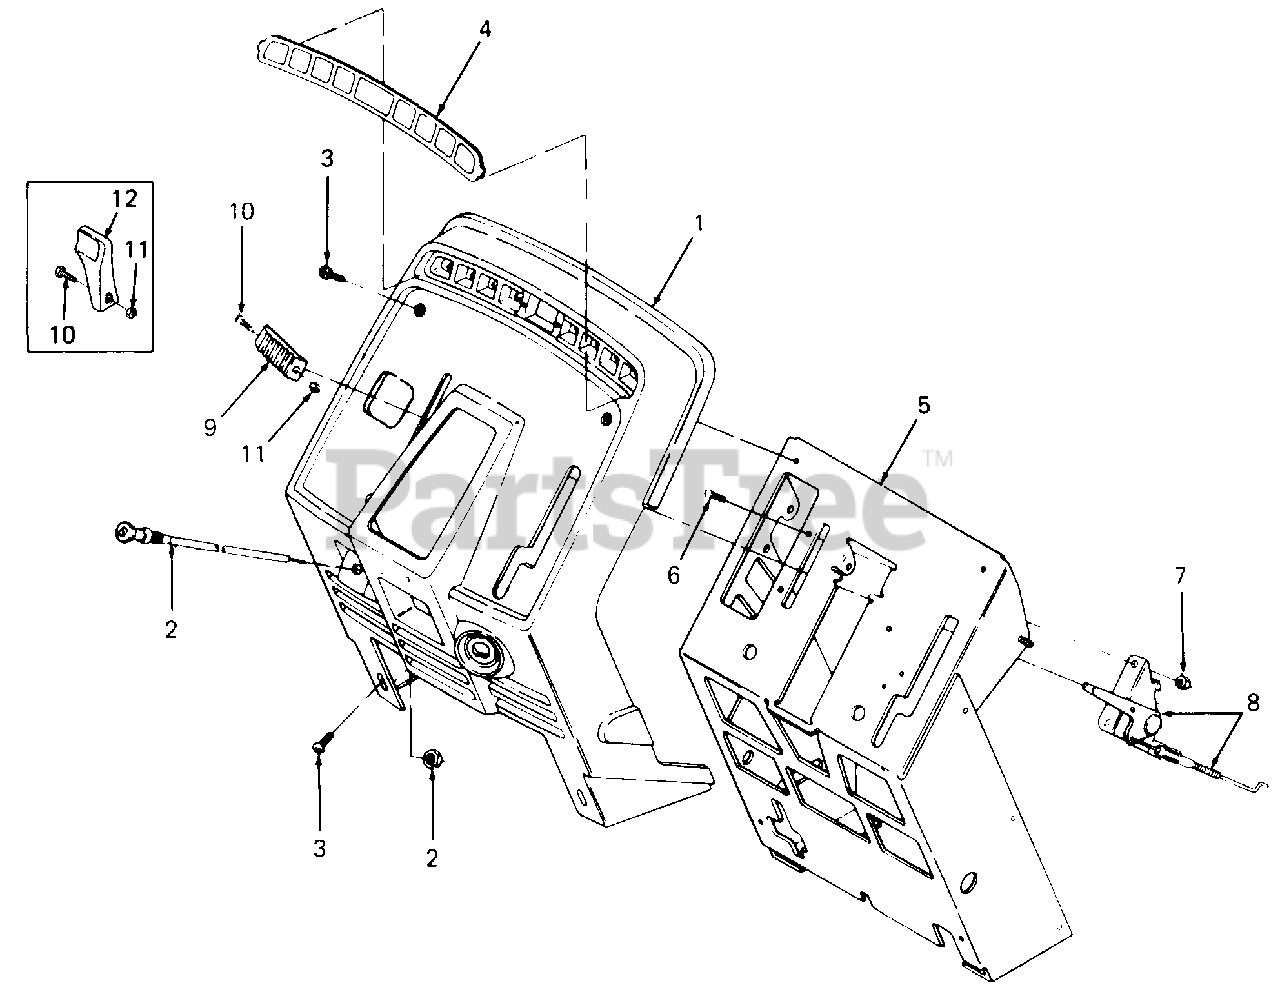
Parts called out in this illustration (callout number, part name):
1	Panel, Instrument
2	Choke Cable w/Nut
3	Screw, Pan Hd Cutting, #10-24 X .75 Lg
4	Label, Dash
7	Nut, Hex Keps, #10-32
8	Control, Throttle
9	Knob, Throttle
10	Screw, Cross Rec Truss Hd, #8-32 X .38 Lg
11	Nut, 8-32
12	Knob, Throttle
